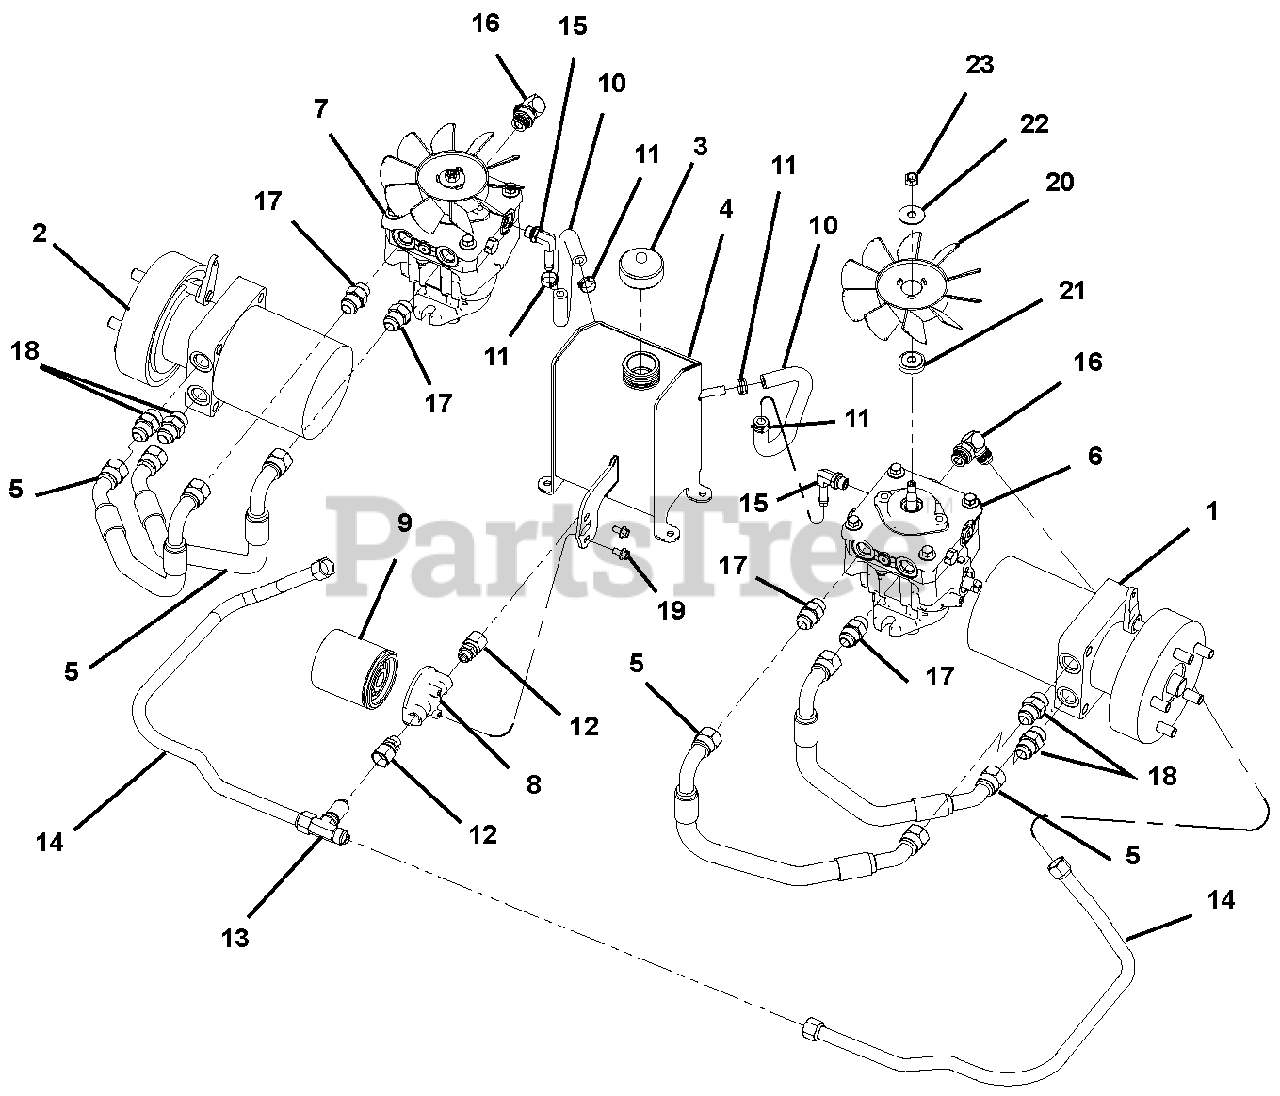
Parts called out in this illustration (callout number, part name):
1	Motor, Left Hand Wheel
2	Motor, Right Hand Wheel
3	Cap, Oil Reservoir Breather
4	Weldment, Oil Tank
5	Hose, Hydraulic 5/8 x 18.75
6	Pump, LH BDP16A
7	Pump, RH BDP16A
8	Head, Filter
9	Filter, 25 MICRON
10	Hose, Hydraulic 3/8 x 12.5 Long
11	Clamp, .690 OD Hose PINCH
12	Fitting, #6 Male OR x #8 Female 37° JIC
13	Fitting, Bulk Head #8 JIC Tee
14	Hose, #8 TOC W/ # 8 SWL 37°JIC
15	Fitting, 9/16 MOR x 3/8 Hose 90º
16	Fitting, HYD Elbow 3/4 O-RING, 3/4JIC
17	Adapter, 3/4-16MOR x 7/8-14JIC
18	Adapter, 7/8-14MOR x 7/8-14JIC
19	Bolt, 1/4-20 x .500 WSH 5
20	Fan, BDP16 Plastic Cooler
21	Hub, BDP16 Fan
22	Washer, .375 x 1.25 x .072 Bellville
23	Locknut, .38-24 Crown
NS	Lever, S/O
NS	Kit, Motor Seal - DF280 S/O
